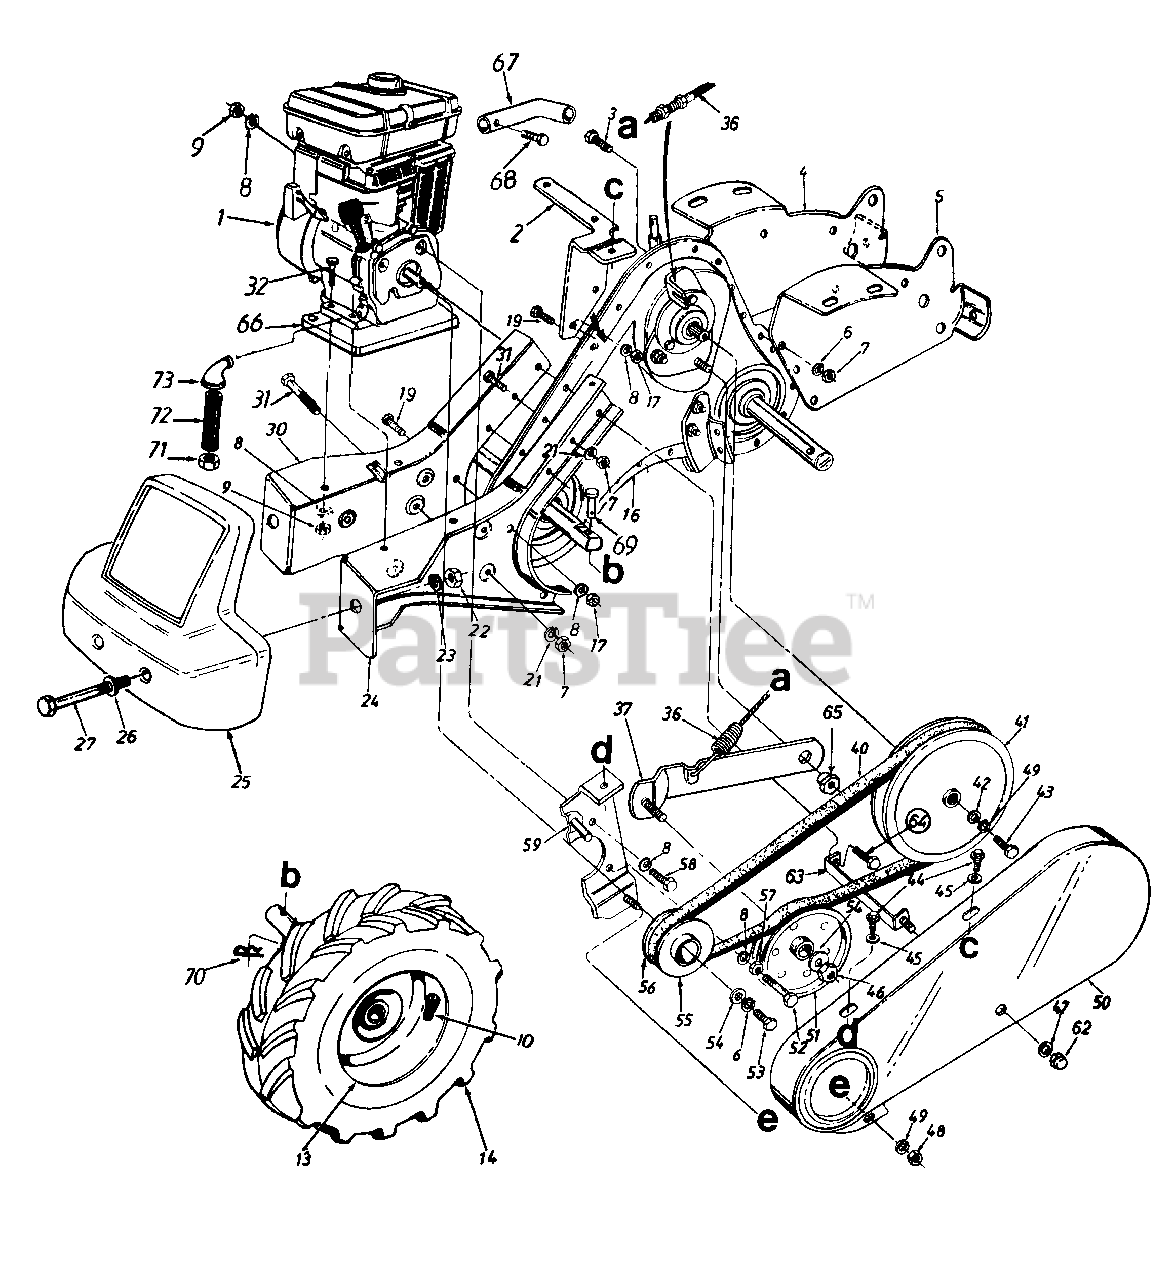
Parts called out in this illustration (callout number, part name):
1	Engine
7	Hex Nut 3/8-16 Thd.
8	L-Wash. 5/16" I.D.
10	Air Valve
16	Gear Case Ass'y. Comp.
17	Hex Nut 5/16-18 Thd.
19	Hex Bolt 5/16-18 x .75" Lg.
21	L-Wash. 3/8" I.D.- H.D.
22	Hex Nut 1/2-13 Thd.
23	L-Wash. 1/2" I.D.
26	Fl-Wash. .510" I.D. x 1.0"
27	Hex Bolt 1/2-13 x 5.00" Lg.
32	Hex Bolt 5/16-18 x 2.75"
36	Clutch Control Cable 46" Lg.
37	Idler Bracket Ass'y.
40	"V"-Belt
41	Fl-Pulley 8" O.D.
42	Fl-Wash. 1/4" I.D. x .93" O.D.
43	Hex Bolt 1/4-28 x .75" Lg.
44	Hex Wash. Hd. S-Tap Scr. 1/4-20 x .50" Lg.
45	Fl-Wash. .281" I.D. x .625"
46	Hex Cent. L-Nut 3/8-24 Thd.
47	Fl-Wash..266" I.D. x .625" O.D.
48	Hex Nut 1/4-20 Thd.
49	L-Wash. 1/4" I.D.
51	Fl-Idler w/Flanges 3.75" O.D.
52	Hex Bolt 5/16-24 x 1.75"
53	Hex Bolt 3/8-24 x 1.00" Lg.
54	Fl-Wash. 3/8" I.D. x 1.00"
55	Outer Engine Pulley Half
56	Inner Engine Pulley Half
57	Hex Nut 5/16-24 Thd.
58	Hex Bolt 5/16-24 x .62" Lg.
59	Belt Keeper Ass'y.
62	Hex Cap Nut 1/4-28 Thd.
63	Belt Cover Brkt. Ass'y.
64	Hex Bolt 5/16-18 x 1" Lg. (Gr. 5)
65	Shld. Nut
66	Engine Spacer Block
67	Outlet Pipe
68	Hex Wash. Hd. AB-Tap Scr. #8 x .5" Lg.
69	Clevis Pin
70	Hairpin Clip
71	Oil Cap 1/4" NPT
72	Drain Pipe 1/4" NPT
73	Street Elbow 1/4" NPT
